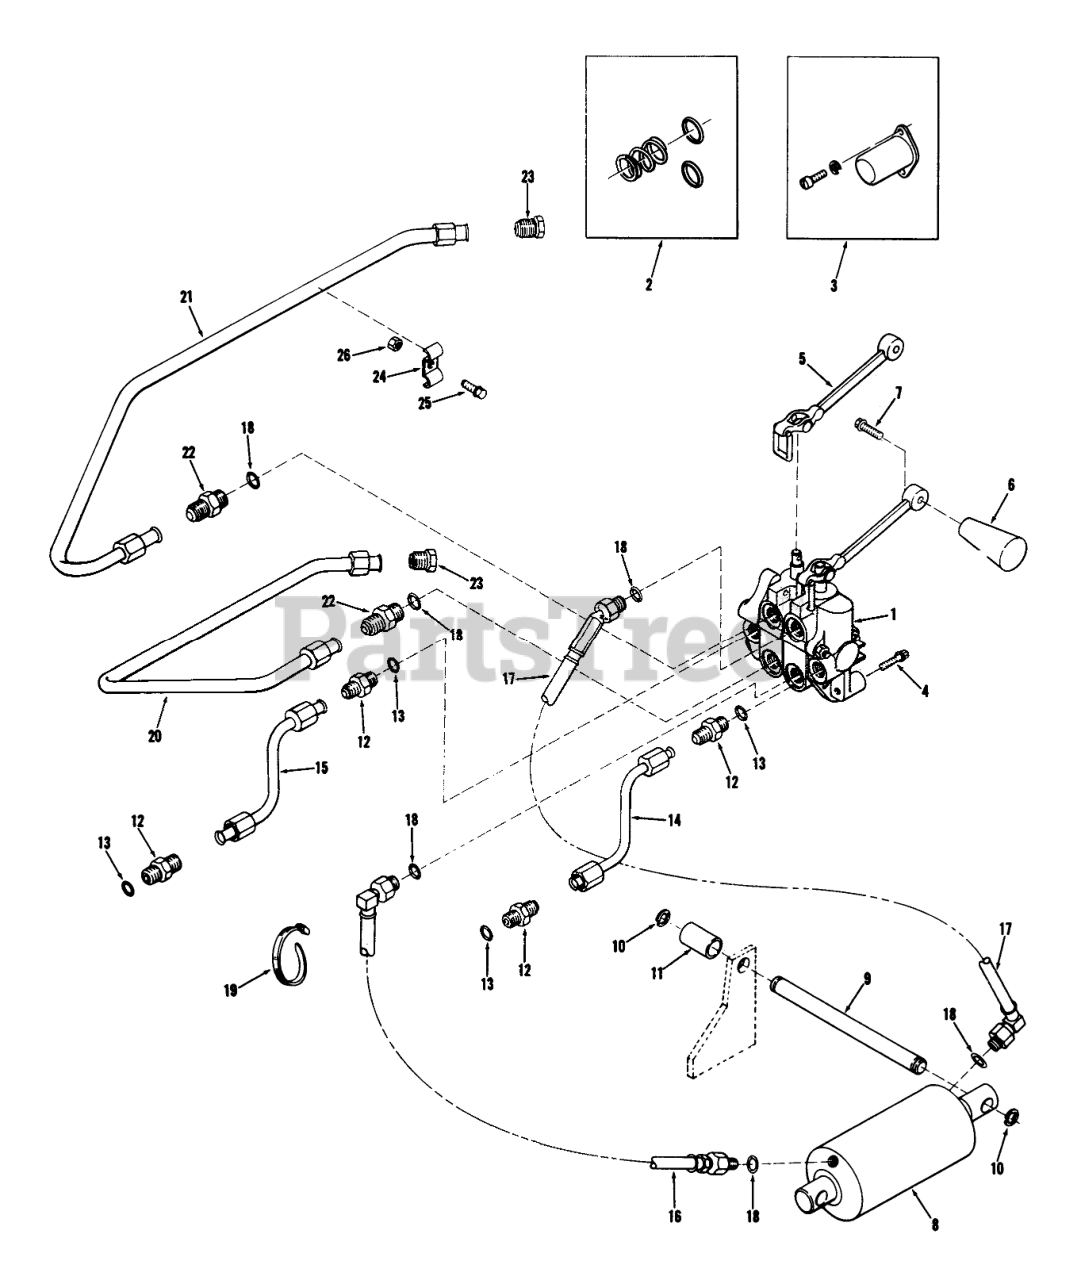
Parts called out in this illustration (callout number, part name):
1	Valve Assy.
2	0-Ring Kit-S.A.
3	Spool Cap Kit
4	Screw
5	Assy-Handle
7	SCREW
8	Cylinder
9	Cylinder Pivot
10	Snap Ring
11	Spacer
12	FITTING
13	0-Ring
14	PRESSURE TUBE ASSY
15	ASSY TUBE PRESSURE
16	ASSY-HYDRAULIC HOSE
17	Hydraulic Hose Assy
18	O RING
19	PLASTIC TIE
20	Front Tube Assy
21	Rear Tube Assy
22	FITTING
24	Clamp Tube
25	Bolt
26	Nut
